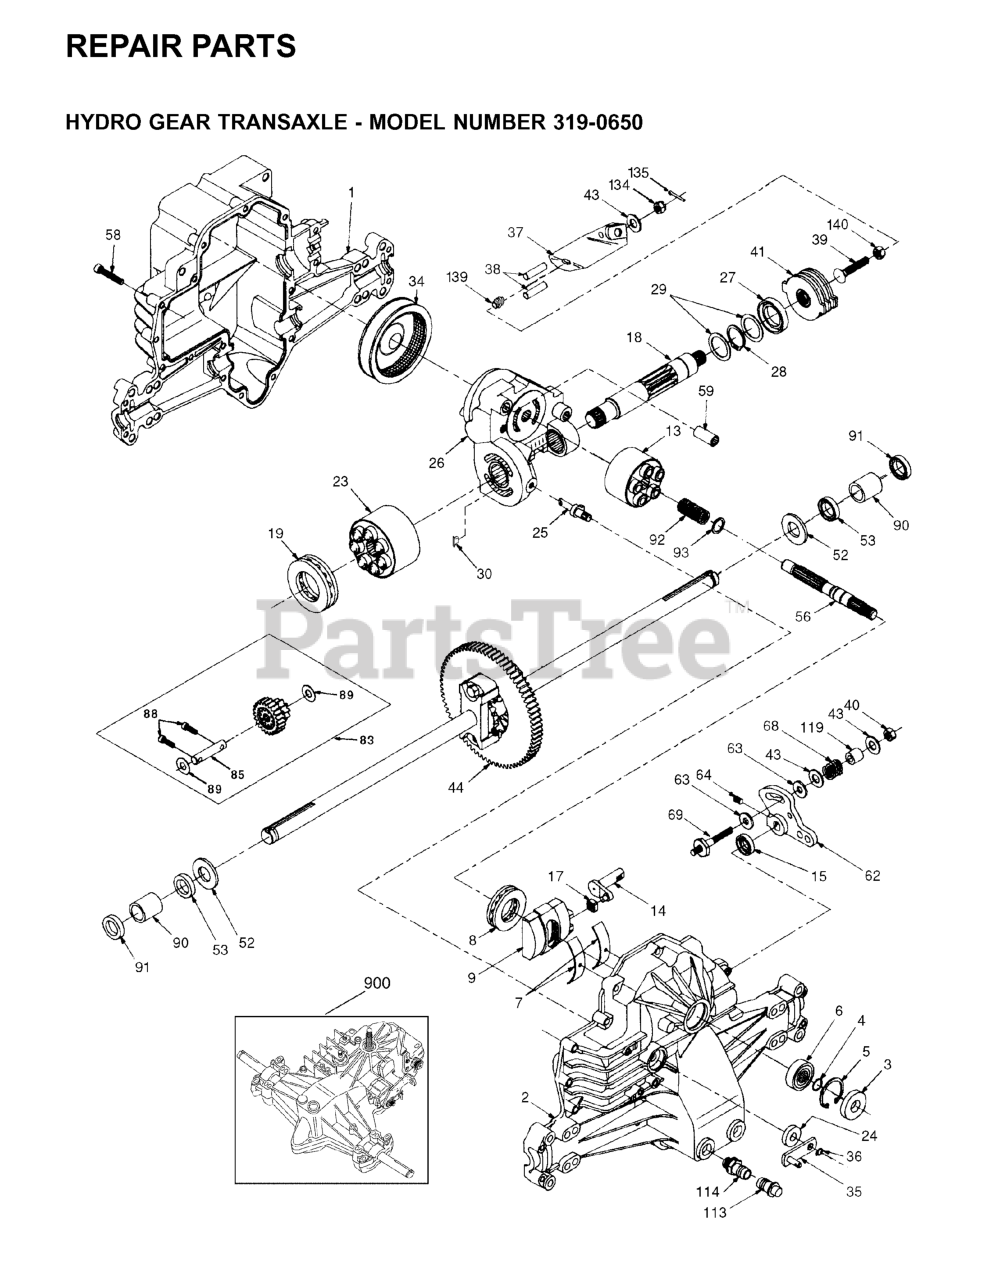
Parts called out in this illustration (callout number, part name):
1	LOWER HOUSING
2	HOUSING UPPER 70255
3	SEAL.LIP.H-G.(9008000-0128)
4	RING RETAINING 2003016
5	RING.RETAINING.(2003052)
6	BALL BEARING
7	CRADLE BEARING
8	BEARING, THRUST 50551
9	SWASHPLATE (2003087)
13	BLOCK, CYL ASSY
14	TRUNNION ARM
17	SLOT GUIDE
18	SHAFT, MOTOR
19	BEARING, THRUST 50552
23	BLOCK, CYL ASSY
25	BYPASS ACTUATOR
26	CENTER SECTION ASS'Y KIT
28	RETAINING RING
34	ELEMENT, OIL FILTER
35	BYPASS ARM
36	RETAINING RING 44870
37	ACTUATING ARM
38	ACTUATING PIN 44891
39	BOLT 5/16-24 X 1-3/4
40	LOCKNUT, HEX 5/16-24
41	BRAKE ROTOR 70135 HYDRO-GEAR
43	WASHER .34X.88X.06.44130
44	KIT SVC DIFFRENTIAL 70130
52	WASHER.HYDRO-GEAR 44875
53	SEAL.HYDRO.53901
56	SHAFT.INPUT.50005
58	BOLT #44876
62	CONTROL ARM 50254
63	DAMPENER PUCK
64	SCREW.SET.50018
68	SPRING HELICAL COMP 50277
69	STUD 5/16-24 50284
83	JACK SHAFT ASSY
89	WASHER 50132
90	SLEEVE.BEARING 50118
91	RP SEAL, WIPER
92	SPRING 2003014
113	CAP, VENT ASSY
114	O-RING KIT 70110
119	SPACER.HYDRO GEAR 50278
134	NUT.CAS.HYD.44142
135	ID DOT HYDD
139	SPRING, COMPRESSION 50431
140	NUT, HEX 5/16-24
900	TRANSAXLE ASSEMBLY
